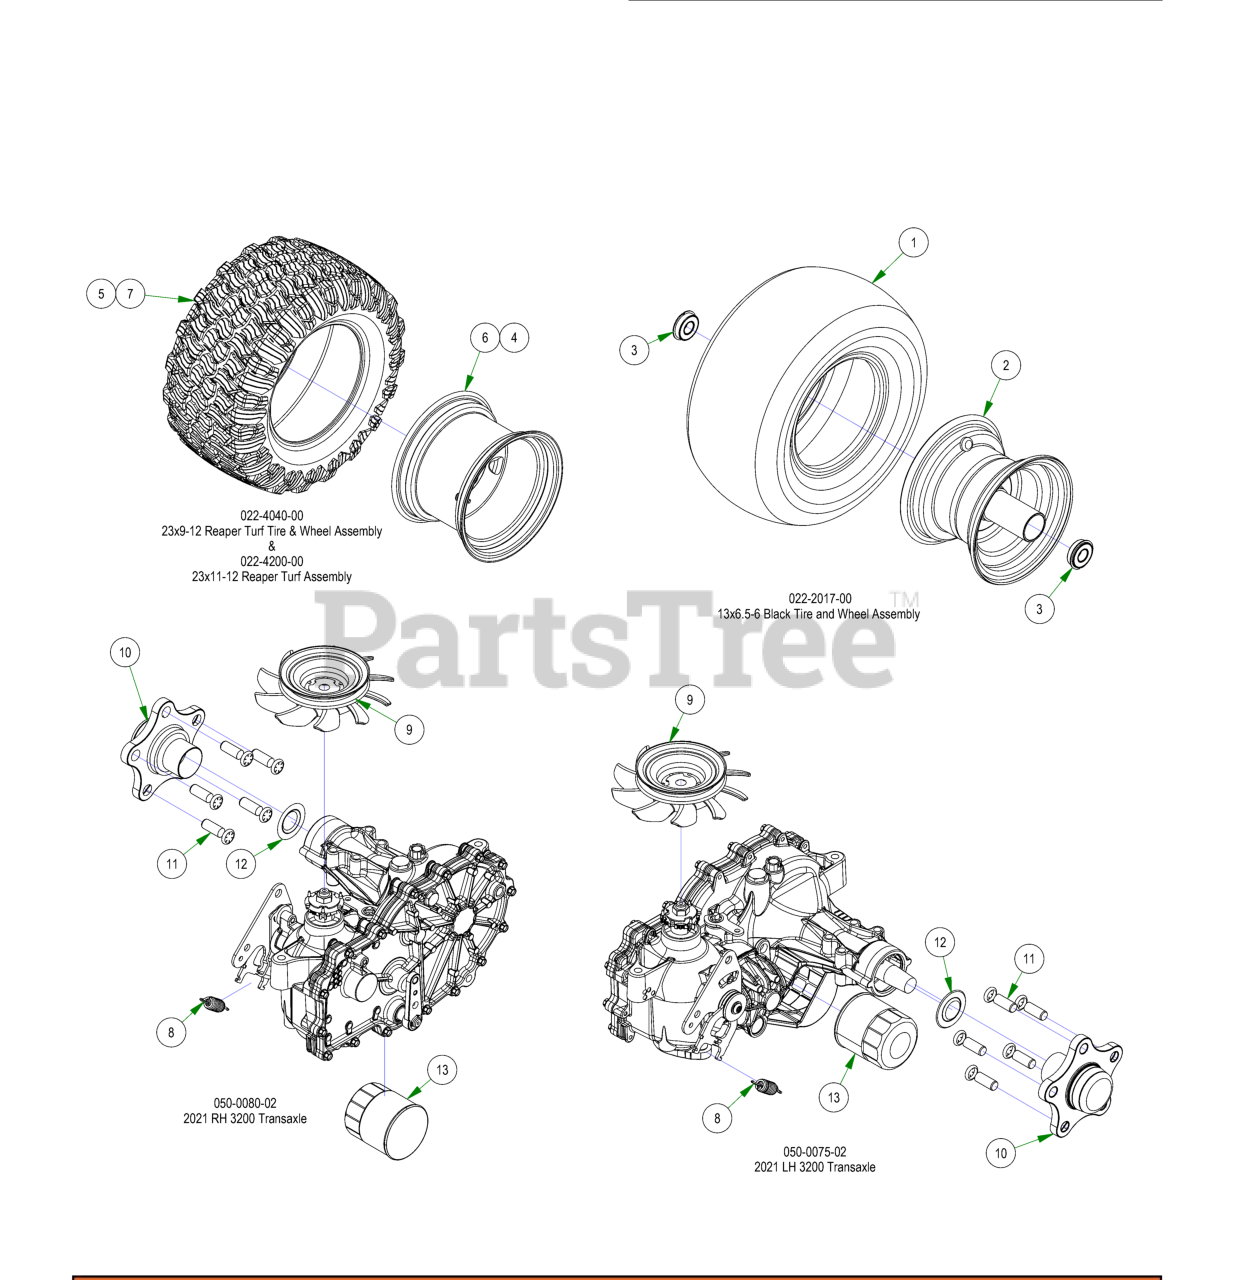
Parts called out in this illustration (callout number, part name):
1	13 x 6.50 - 6 Tire
2	Front Tire Rim
3	Ball Bearing w/Retainer, 99502H-NR, .625 Bore x 1.375 OD x .4375 Width
4	12x7" Black Wheel
5	23x9-12 Reaper Turf Tire Only
6	12x8.5 Black Wheel
7	Tire, 23/11x12 Reaper Turf
8	Gold Transaxle Spring
9	2021 ZT/Maverick Transaxle Fan/Pulley Kit
10	5 Bolt Hub Kit
11	Transaxle Wheel Studs/ Drum Brake Studs
12	2021 ZT/Maverick Transaxle Seat Kit (ZT-2800)
13	ZT Hydraulic Filter
